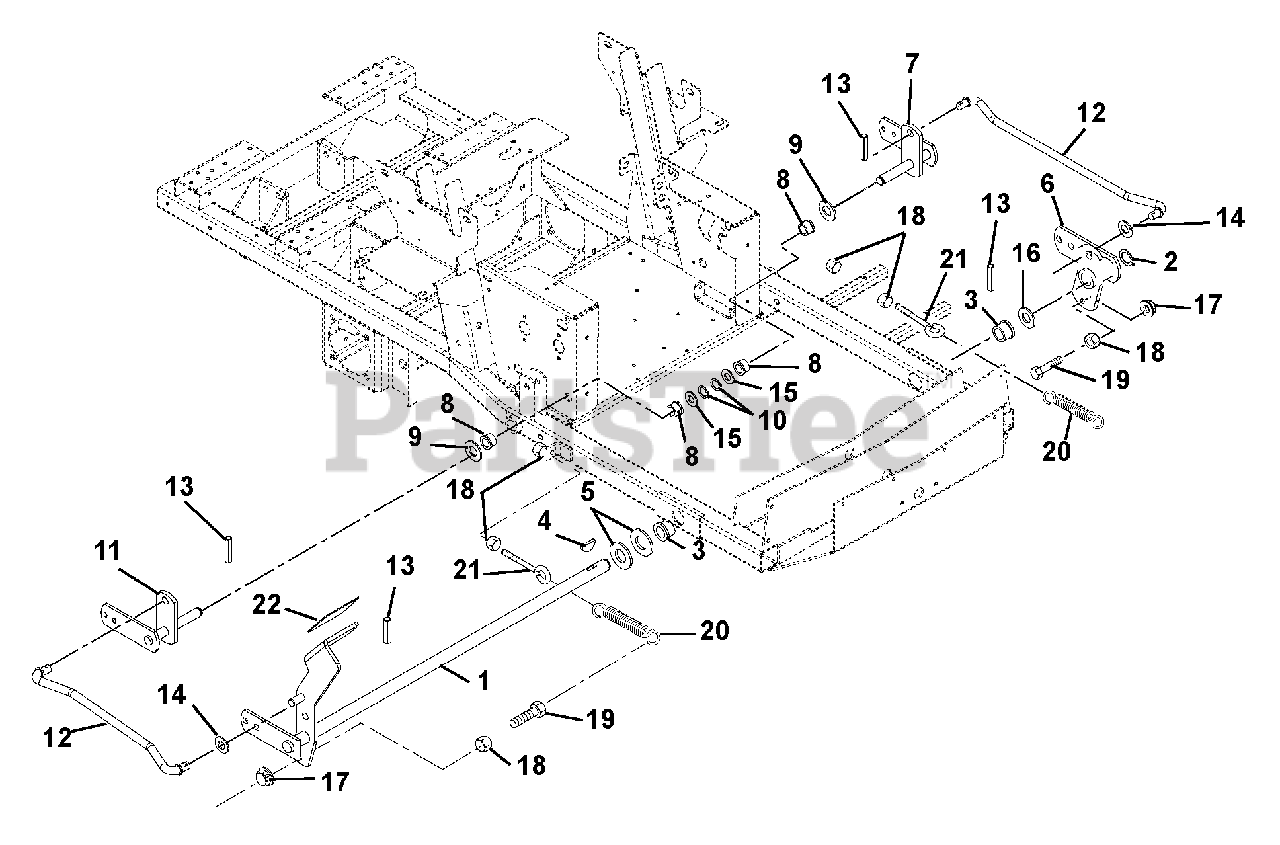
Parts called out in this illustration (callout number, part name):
1	Lift, Mower
2	Ring, Retaining External 1.00 x .078
3	Bushing, Flange Nylon 1.020 x 1.385 x .75 x 1.75
4	Key, Woodruff .25 x 1.00
5	Washer, Flat Steel 1.062 x 2.00 x .134
6	Weldment, Lift Arm Front
7	Weldment, Lift Arm Shaft Left Hand
8	Bushing, Flange Nylon .762 x 1.00 x .58 x 1.48
9	Washer, Hardened Steel .758 x 1.23 x .031
10	Ring, Retaining External .689 x .077
11	Weldment, Lift Arm Shaft Right Hand
12	Rod, Lift Assist
13	Pin-Roll .250 x 1.25 Stainless Steel
14	Washer-Flat-Steel .630 x 1.25 x .062
15	Washer, Flat Steel .755 x 1.25 x .125
16	Washer, Hardened Thrust 1.00 x 1.55 x .03
17	Nut, Locking-Top-Flange .38-16
18	Nut, Hex .38-16
19	Bolt, Hex .38-16 x 1.75 Grade 5
20	Spring, Tension .162 x 1.25 x 8.25
21	Bolt, Eye .375-16 x 2.50
22	Grip, Foot Pedal 1.50 x 3.00
